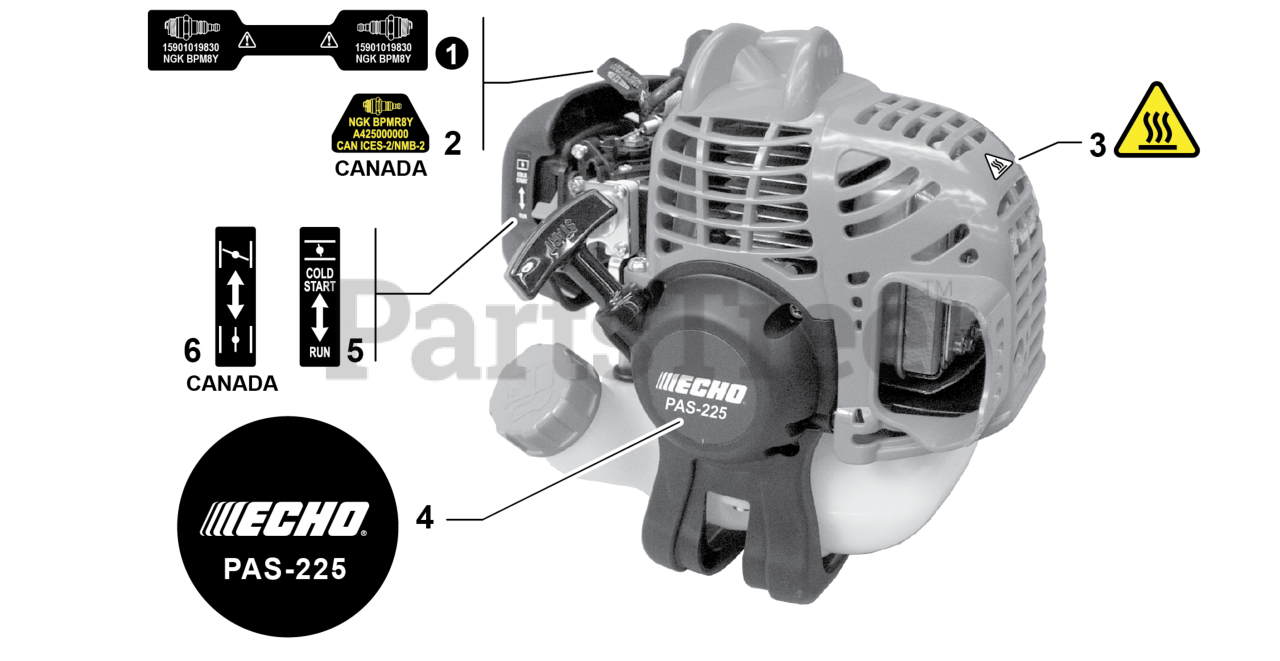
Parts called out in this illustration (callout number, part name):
1	LABEL - SPARK PLUG - BPM8Y
2	LABEL - SPARK PLUG - BPMR8Y
3	LABEL - CAUTION - HOT
4	LABEL - MODEL PAS-225
5	LABEL - CHOKE
6	LABEL - CHOKE
